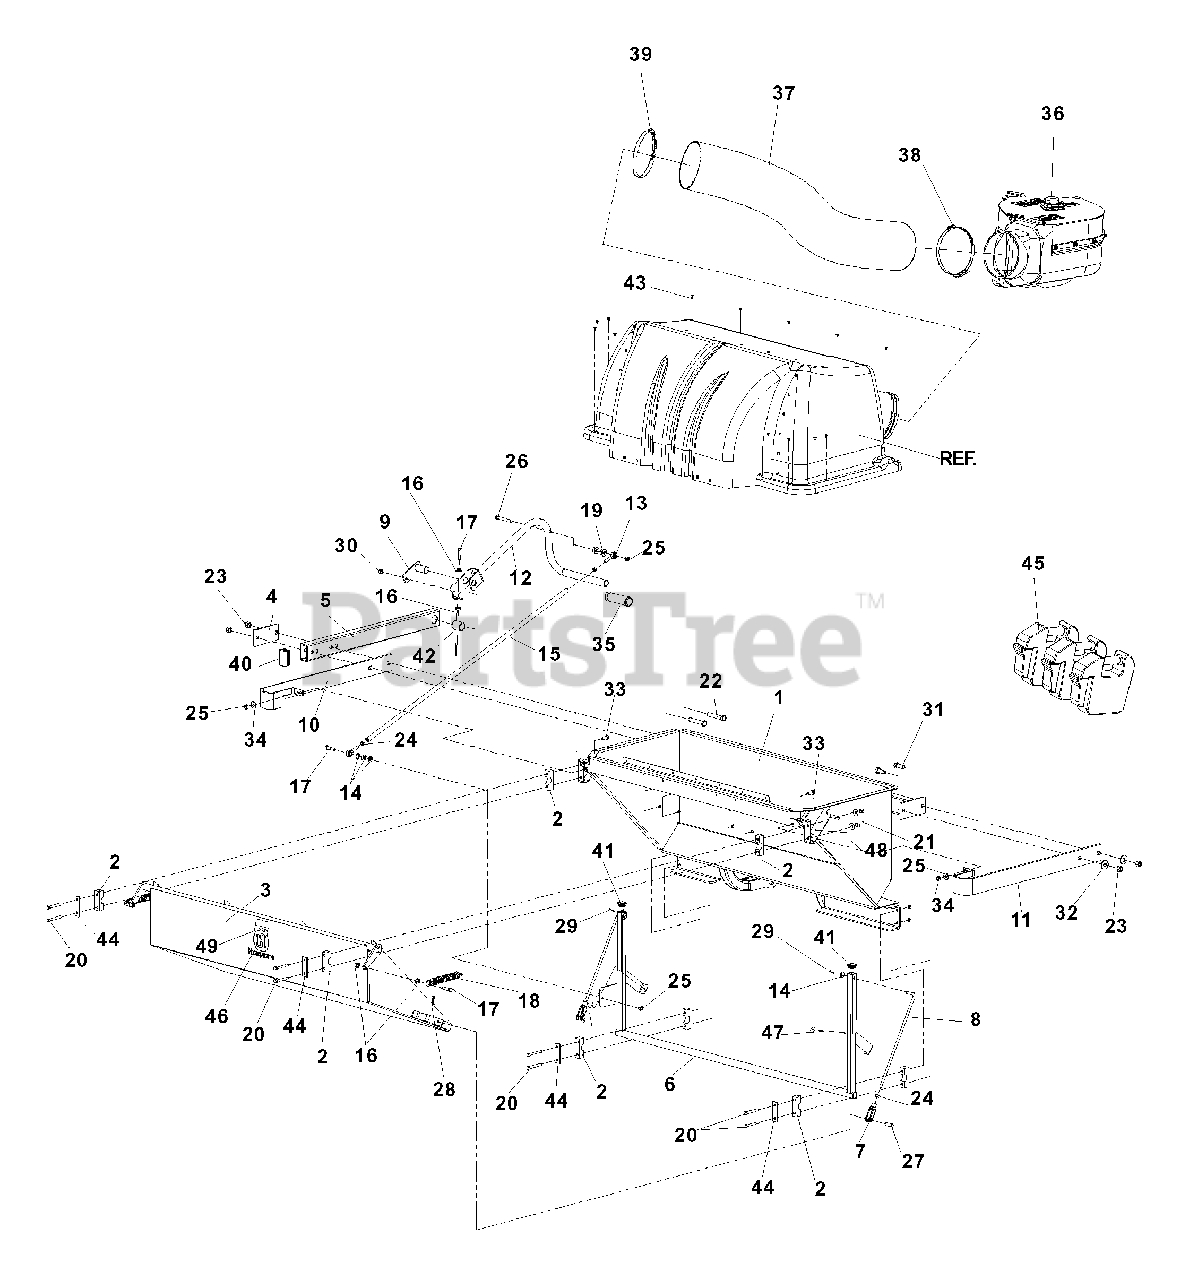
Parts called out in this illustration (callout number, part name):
2	PILLOW BLOCK
4	PLATE - BACKING
5	TUBE, SUPPORT, HANDLE
6	BELL CRANK
7	YOKE, 3/8 F
9	PIN, PIVOT
10	GUARD, LEFT
11	GUARD, RIGHT
13	ROD END, 3/8 -24, RH
14	WASHER, 3/8 , SAE
15	TUBE, THREADED
16	NUT, 3/8 -16, WHIZLK
17	HCS, 3/8 -16 x 1 1/2,
20	HCS, 5/16 -18 x 2 3/4,
21	NUT, 5/16 -18, NYLOC
22	HCS, 1/2 -13 x 3,
23	NUT, 1/2 -13, NYLOC
24	NUT, 3/8 -24, JAM
25	NUT, 3/8 -16, NYLOC
26	HCS, 3/8 -16 x 3,
27	PIN CLEVIS, 3/8 x 1 1/4
28	HAIRPIN COTTER
29	PIN, COTTER, 1/8 x 3/4
30	NUT, 1/4 -20, NYLOC
31	HCS, 1/2 -13 x 1 1/4,
32	WASHER, 1/2
33	HCS, 3/8 -16 x 1,
34	WASHER, 3/8
35	GRIP, HANDLE
36	BLOWER
38	OVER CENTER BAND
39	HOSE CLAMP, 6"-7"
40	PLUG, RECT TUBING
41	PLUG, SQUARE TUBE
42	BUSHING, 1"
44	REINFORCEMENT BAR
45	WEIGHT CAST, FRONT
46	DECAL, CROWN
47	GROMMET, BUMPER
48	WASHER, 5/16
49	DECAL, VENTILATION
